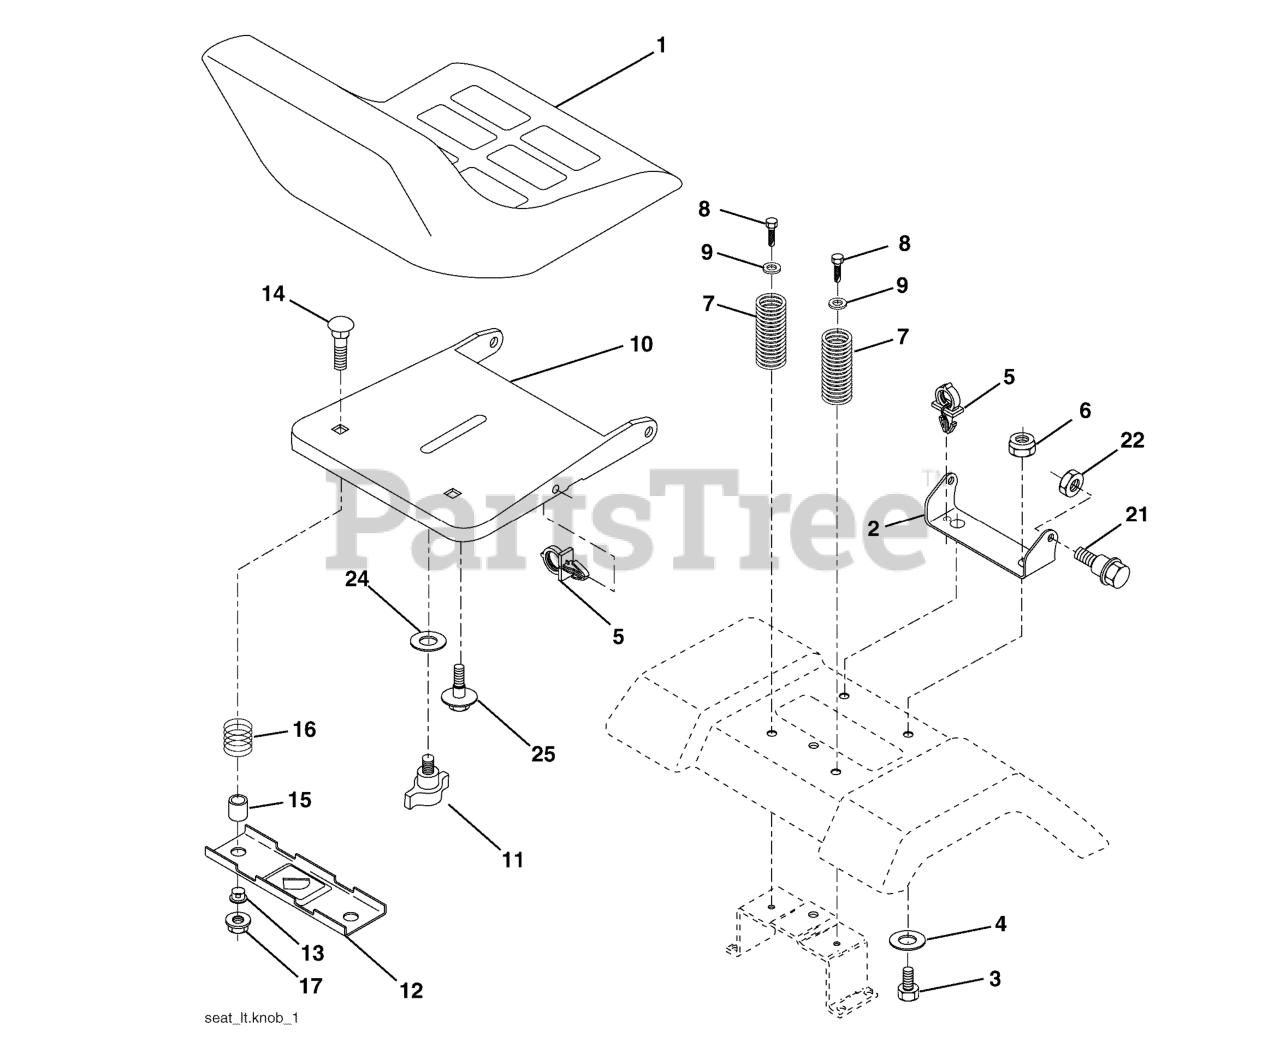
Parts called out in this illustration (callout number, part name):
1	SEAT.XH150.GRY
2	SEAT PIVOT BRKT
3	BOLT, HEX 3/8-16X1
6	NUT
7	SPRING COMPRESSION
8	SCREW 3/8-16X1
9	WASHER
10	PAN SEAT
11	KNOB.SEAT.ADJ.WINGNUT
12	BRKT.MNTNG.SWITCH.SEAT.BLACK
14	BOLT.ROUND.HEAD.SQUARE.NECK
16	SPRING COMPRESSED
17	NUT T
21	BOLT.SHOULDER.5/16-18
22	NUT.71038.31-18.HEX.NYLOCK
25	BOLT,SHOULD
